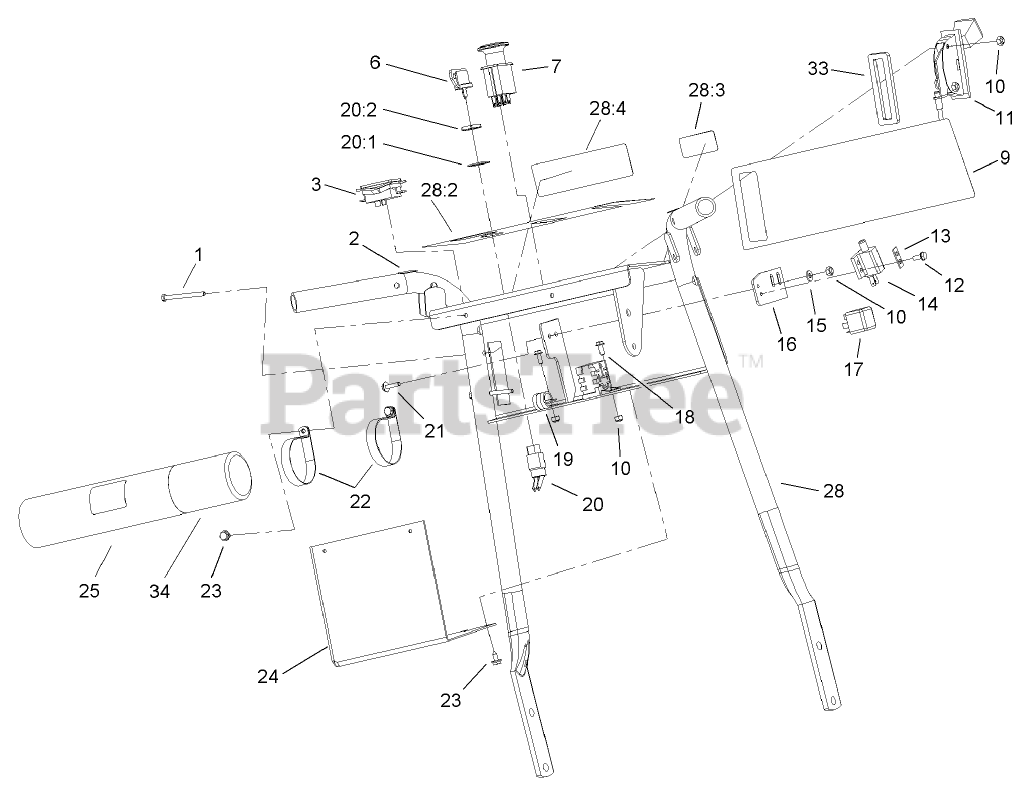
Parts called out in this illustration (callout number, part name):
1	SCREW-SHH
2	DECAL-LOCK, NEUTRAL
3	HOURMETER
6	KEY-IGNITION
7	SWITCH-PTO
9	DECAL-CONTROL, THROTTLE
10	NUT-LOCK, NI
11	CONTROL-THROTTLE
12	SCREW-TAPTITE
13	PLATE-SWITCH
14	SWITCH-POLE, SINGLE
15	WASHER-FLAT
16	PLATE-MOUNTING, SWITCH
17	RELAY
18	SCREW-HWH
19	CLAMP-R
20	Key Switch ASM
20:1	WASHER-TOOTH, INTERNAL
20:2	NUT-HH
21	SCREW-HWH
22	CLAMP-R
23	SCREW-HWHTF
24	BRACKET-COVER
25	TUBE-MANUAL
28	HANDLE ASM
28:2	DECAL-PANEL, CONTROL
28:3	DECAL-PROTECTION, EAR
28:4	DECAL-WARNING
33	GASKET-THROTTLE
34	CAP-HOUSING
